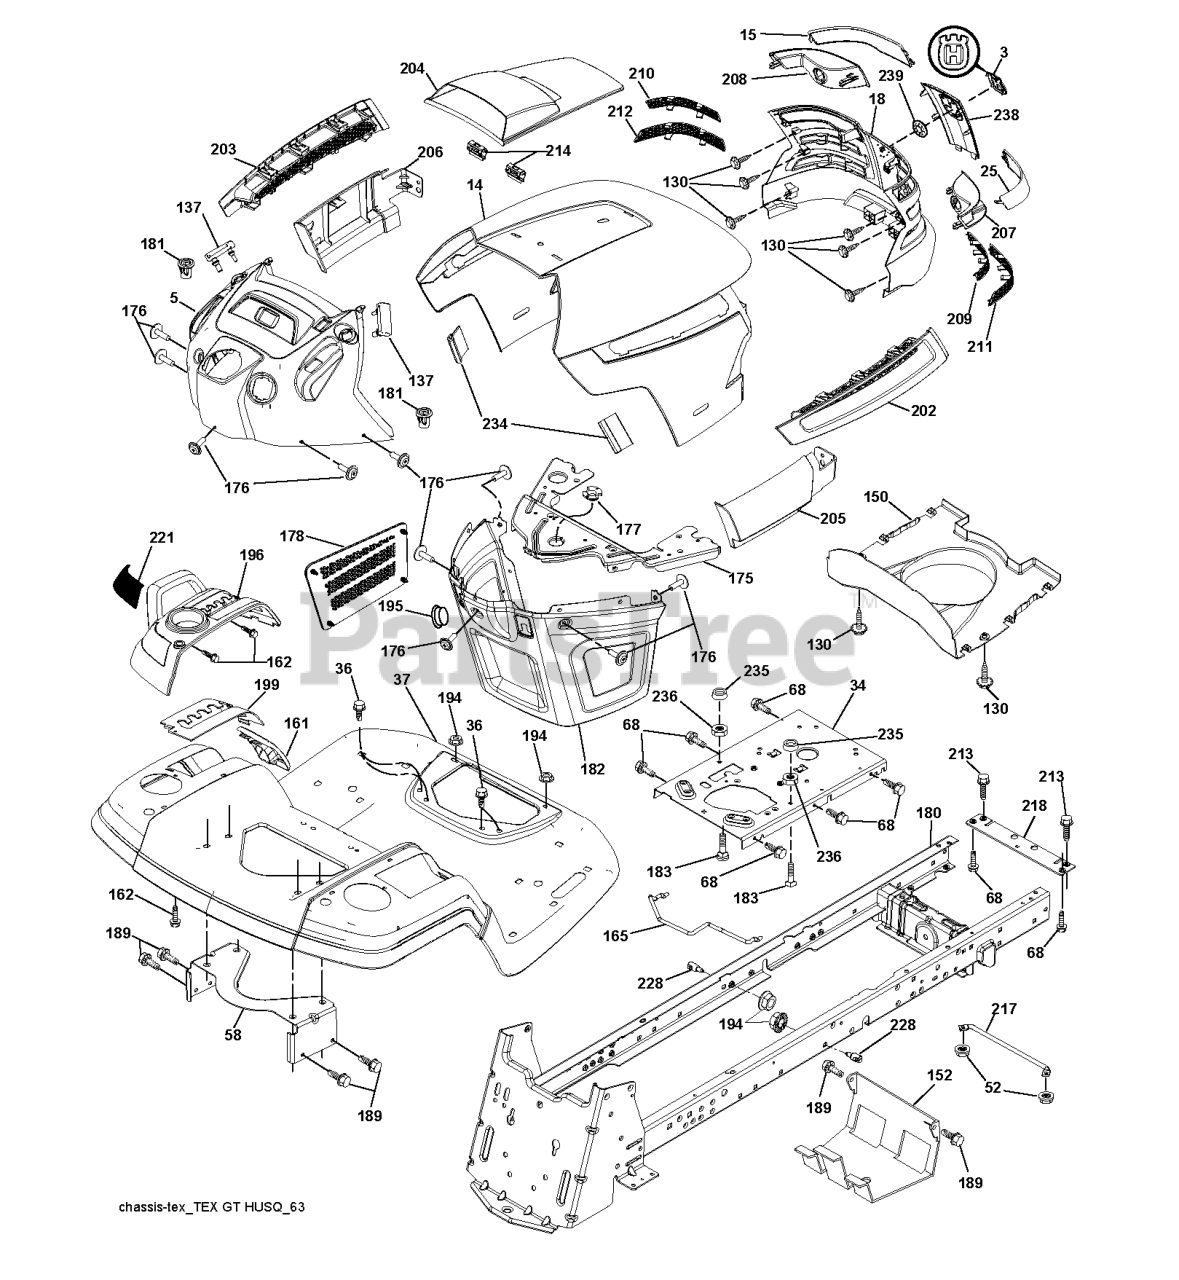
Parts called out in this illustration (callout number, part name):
3	RP LOGO
5	DASH.HUSQ.UPR.ELE.SVMD
14	HOOD.ASM.HUSQVARNA.GT.TEX.ORAN
15	LENS.LH.TEX.GT.HUSQ.CL
18	GRILL.ASM.HUSQ.TG/CRD.W/TRIM
25	LENS.RH.TEX.GT.HUSQ.CL
34	PLATE.ENGINE.WELDED.CHASSIS
36	SCREW 5/16"
37	FENDER.PNT.TX.GT.CH/FW/DL.HUSQ
52	LOCKNUT
58	BRKT.SUPPORT.FNDR/TANK
68	SCREW LT
130	SCREW.#10 X 0.750.BOS
137	BUMPER DASH
150	AIR.DUCT.HOOD.TEX.GT.HUSQ
152	SHIELD.BROWNING.W/TEX
161	CONSOLE.WINDOW.FUEL.HUSQ.GT
162	SCREW.HI-LO.CONSOLE
165	SUPPORT.TANK.REAR.W/TEX
175	PLATE.CROSSMEMBER.HUSQ
176	SCREW.#10-24X5/8.RN.QU
177	BUSHING, STEERING
178	CARGO.ASM.NET.TXGT.W/C
180	CHASSIS.GT.SLOPED.DRAWBAR.
181	BUSHING.MNT.FEND.CRGO.TEX.49
182	DASH.LOWER.COMMON.12V.ADAPTOR
183	BOLT.5/16-18X1-1/4 FULL THD
189	SCREW
194	NUT LOCK HEX FLANGE 5/16-18
195	PLUG.HOLE.DASH.LOWER.12V.BLK
196	SUBASM.CONSOLE.HUSQ.GT.DECKLFT
199	PLATE.DECK.LIFT.HUSQVARNA.GT
202	VENT.SIDE.HOOD.RH.HUSQ
203	VENT,SIDE.HOOD.LH.HUSQ
204	VENT.TOP.HOOD.HUSQVARN
205	HOOD SIDE SKIRT RH
206	SKIRT.HOOD.SIDE.HUSQ.L
207	BEZEL.RH.TEX.GT.HUSQ
208	BEZEL.LH.TEX.GT.HUSQ
209	INSERT.HEX.GRILL.HUSQ.GREY
210	INSERT.HEX.GRILL.HUSQ.
211	INSERT.HEX.GRILL.HUSQ.
212	INSERT.HEX.GRILL.HUSQ.
213	BOLT
214	CLIP.RETAINER.TINNER.
217	ROD.PIVOT.HOOD
218	X-PIECE.HOOD.STOP.NON/
221	REFLECTOR.LH.TEX GT HU
228	STUD.FASTNER.W/ANTI-ROTATE
234	BUMPER.HOOD.TEX.HUSQVARNA
235	SPACER FENDER
236	NUT.CENTERLOCK.5/16-
238	TRIM.HUSQ.TG/CRD.SERVICE
239	NUT PUSH M
